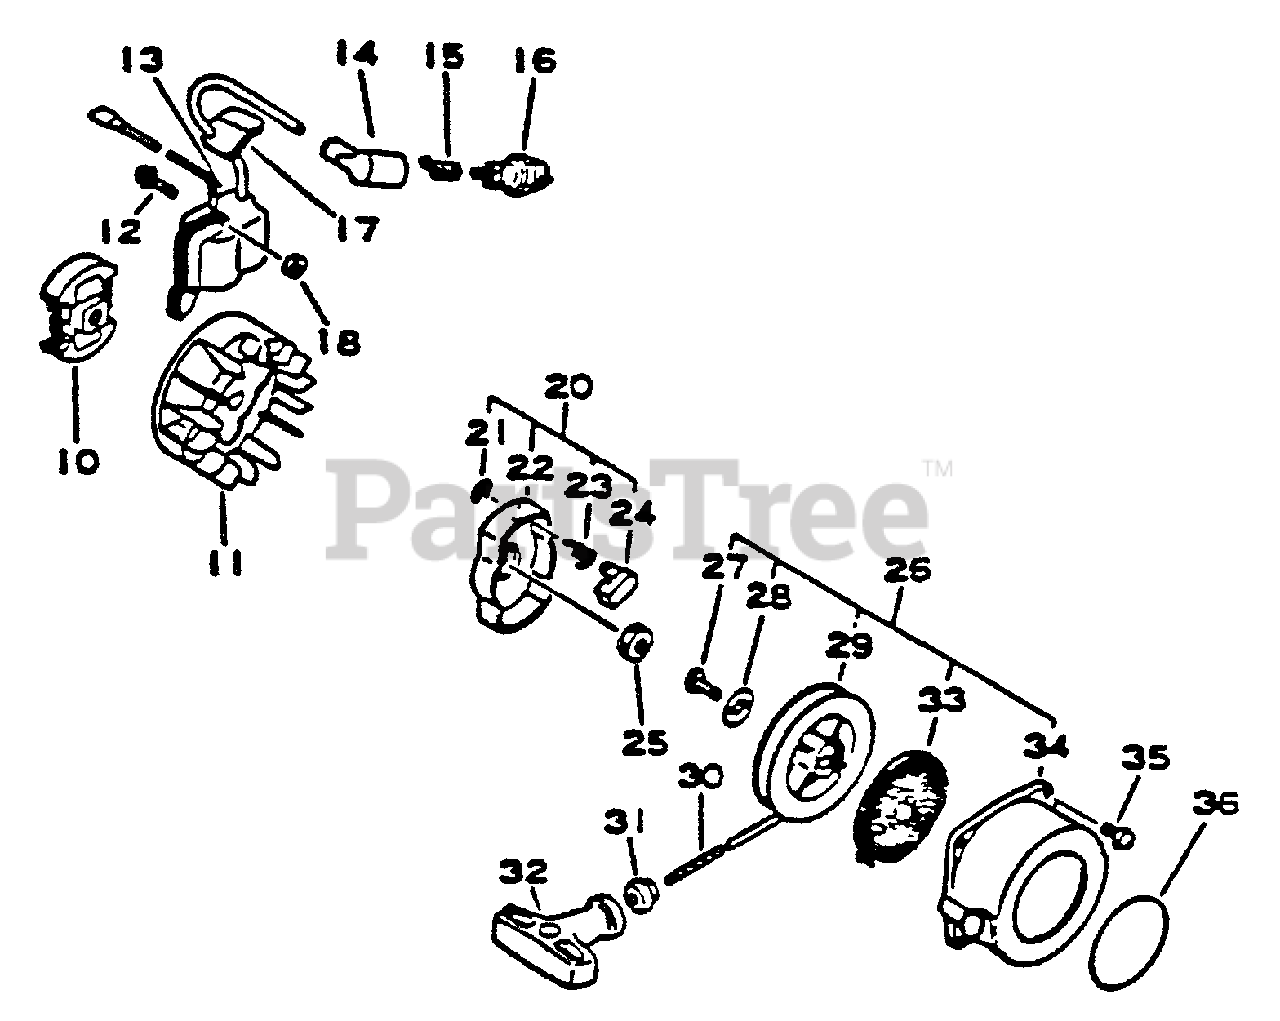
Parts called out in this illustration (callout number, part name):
10	CLUTCH ASSY
11	FLYWHEEL
12	SCREW - 4X22
13	COIL, IGNITION
14	CAP, SPARK PLUG
15	TERMINAL, SPARK PLUG CAP
16	SPARK PLUG -- BPM-7A
17	COVER, DUST
20	STARTER PAWL ASSY
21	RING, RETAINING - 6
22	CATCHER, PAWL
23	SPRING, RETURN
24	PAWL, STARTER
26	STARTER ASSY
28	WASHER
29	REEL, ROPE
30	ROPE, STARTER - 3X890
31	GUIDE, ROPE
32	GRIP, STARTER
33	SPRING, REWIND
34	CASE, STARTER
35	SCREW - 4X16
36	LABEL - ECHO
